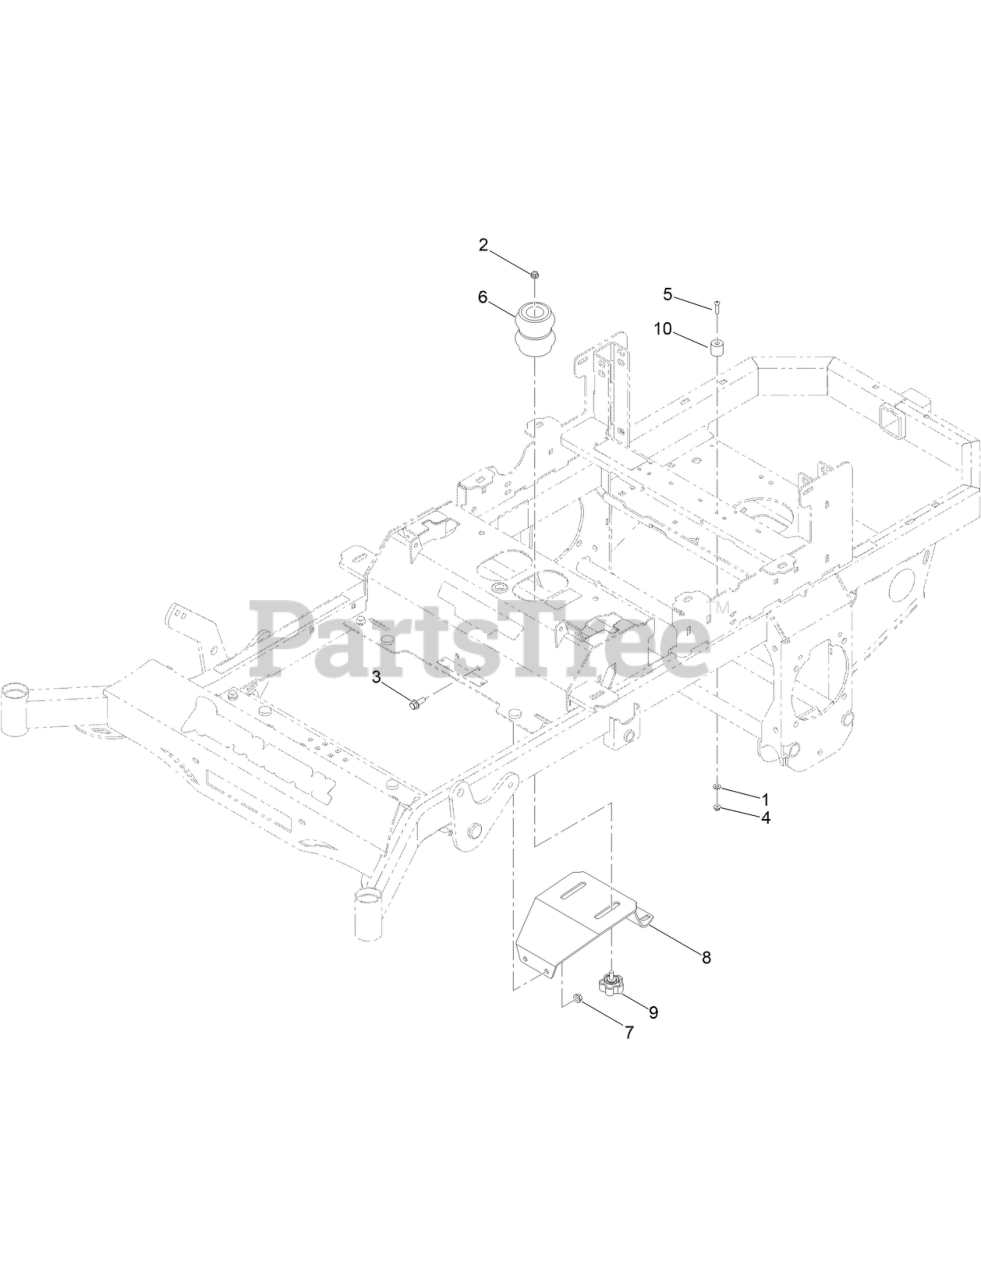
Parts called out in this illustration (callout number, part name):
1	WASHER-FLAT
3	SCREW-HHF
4	NUT-HF
5	1/4-20 X 1 BUTTON SOCKET C/S 18-8 SS
6	SRT RR SUSP AND SEAT FT ELASTOMER TCB-3
7	3/8-16 HEX FLANGE NUT W/SERR ZINC YELLOW
8	MWR SEAT SUSP BRKT (SRT) PAINTED
9	5/16-18X3/4 SL 5-LOBE MALE KNOB 1.90 DIA
10	HOOD REST RUBBER BUMPER
